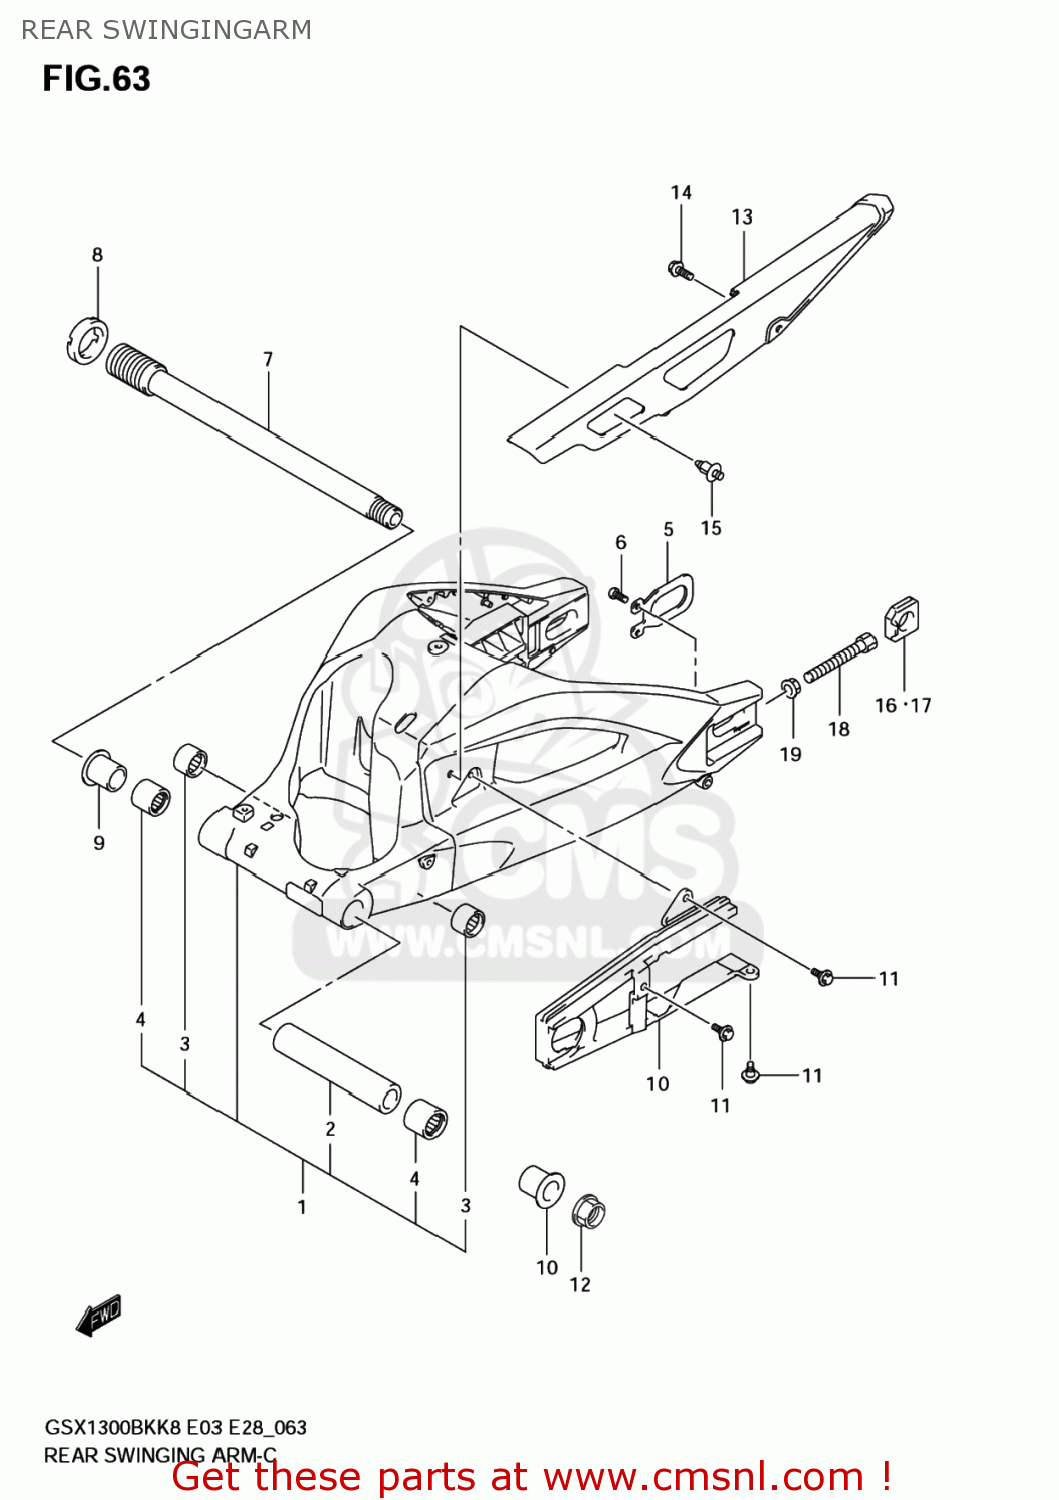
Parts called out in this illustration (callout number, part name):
1	SWINGINGARM AS
2	SPACER,RR SWG PVT CTR
3	BEARING(17X24X25)
4	BEARING(27X35X35)
5	PLATE,RR SWING ARM BRKT
6	SCREW(6X16)
7	SHAFT,RR SWINGINGARM PIVOT
8	NUT,RR SWGARM PIVOT BOLT
9	SPACER,RR SWGARM PIVOT BEARING
10	BUFFER,CHAIN TOUCH DEFENSE
11	BOLT(6X17.8)
12	NUT
13	CASE,CHAIN
14	BOLT
15	CLIP(BLACK)
16	ADJUSTER,CHAIN,R
17	ADJUSTER,CHAIN,L
18	BOLT(8X50)
19	NUT
